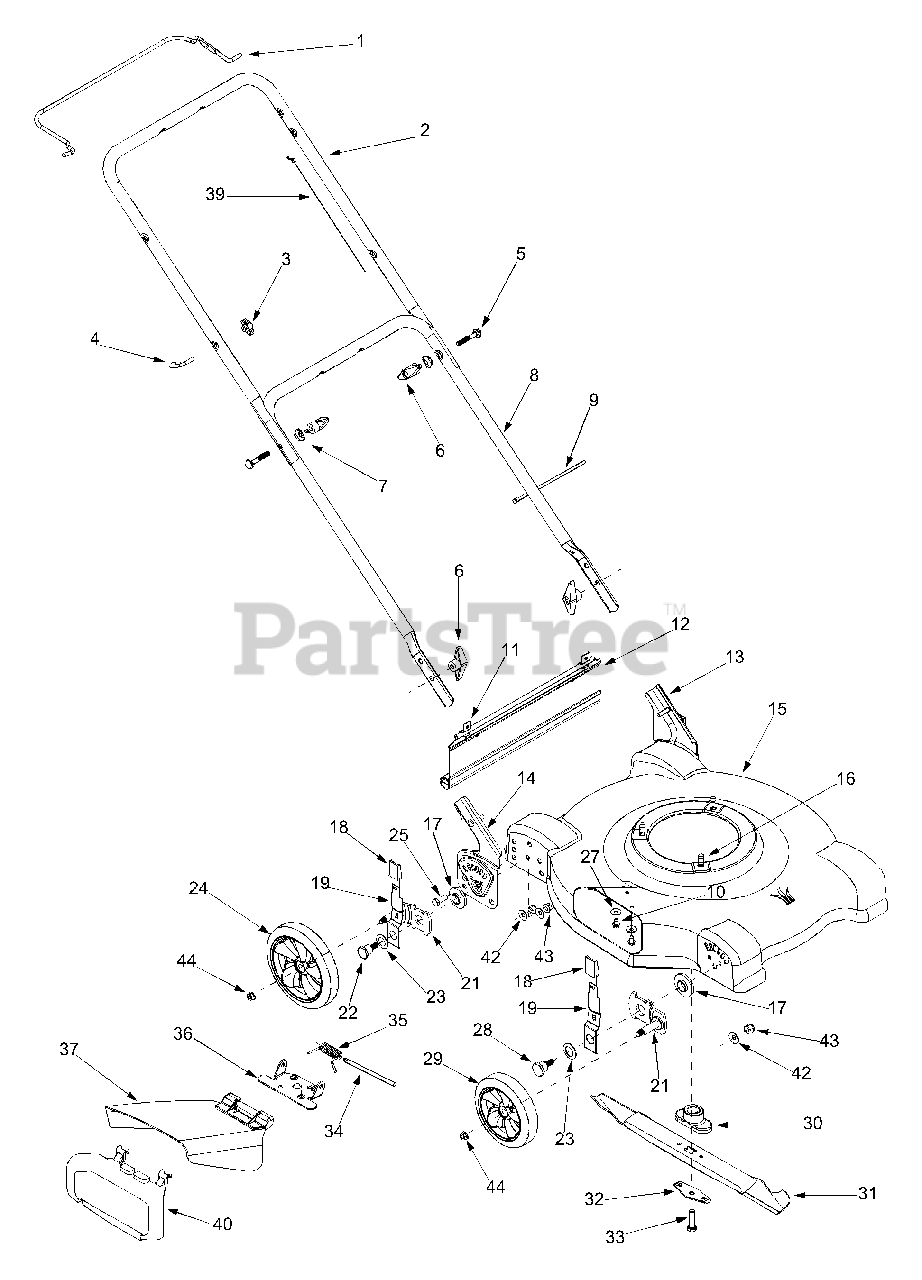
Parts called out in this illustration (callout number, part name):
3	Wing Nut
4	Eye Bolt
5	Carriage Bolt 5/16-18 x 2.0
6	Wing Nut
7	Shoulder Washer .320 ID x .93 OD
9	Cable Tie
10	TT Screw 1/4-20 x 0.5"
11	Hinge Clip
12	Trail Shield
16	TT Screw 3/8-16 x 1.0
17	Height Adjuster Bearing
18	Height Adjuster Knob
19	Lever Assembly
21	Pivot Arm
22	Shoulder Screw
23	Bell Washer .760 ID x 1.25 OD
24	Rear Wheel 8 x 1.8
25	Hex Cap Screw 3/8-16 x 1.0
27	Bell Washer .265 ID x .75 OD
28	Shoulder Screw
29	Front Wheel 7 x 1.8
30	Blade Adapter
31	Standard Blade 22"
32	Blade Bell Support
33	Hex Cap Screw 3/8-24 x 1.5
34	Hinge Pin
35	Torsion Spring
36	Chute Hinge
37	Hinged Chute Deflector
39	Blade Control Cable - 37.25"
40	Mulching Plug (if equipped)
42	Washer Spacer .401 ID x .870 OD
43	Hex Lock Nut 3/8-16
44	Lock Nut 3/8-16
